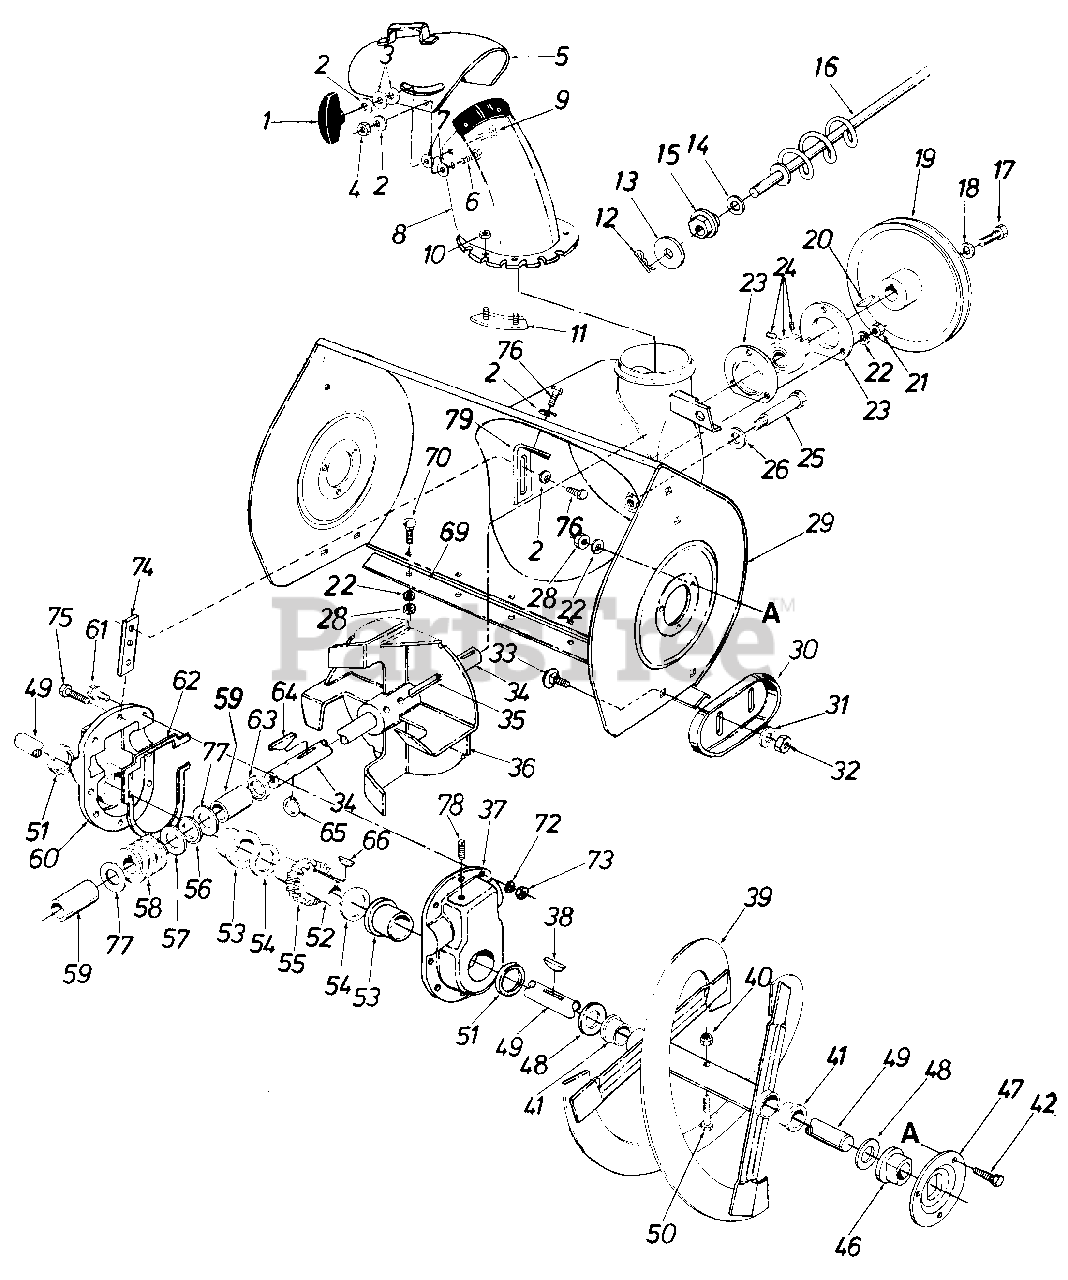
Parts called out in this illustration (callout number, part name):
1	Hand Knob Ass'y.
2	Bell-Wash. .345 0 I.D. x .88 O.D. x .060
3	Fl. Wash. .312 I.D. x 1.125 O.D. x .125
4	Hex Cent. L-Nut 5/16-18 Thd.
5	Top Chute Ass'y.
6	Carr. Bolt 5/16-18 x .62" Lg.
7	Fl-Wash. .53 0 I.D. x 1.25 O.D. x . 1 00
8	Chute Ass'y.
9	Carr. Bolt 5/16-18 x 1.00" Lg.
10	Hex Cent. L-Nut 1/2-20 Thd.
11	Chute Flange Keeper Ass'y.
13	Fl-Wash. .390" I.D. x 1.50" O.D.
14	Fl-Wash. .385" I.D. x .62" O.D.
16	Chute Crank Ass'y.
17	Hex L-Scr. 5/16-18 x .88" Lg.
18	Bell-Wash. .345 0 I.D. x .88 O.D. x .060
19	V-Pulley .875 0 I.D. x 10.12 O.D.
20	#9 Hi-Pro Key 3/16 x 3/4 " Dia.
21	Hex Nut 5/16-18 Thd.*
22	L-Wash. 5/16" Scr.*
23	Bearing Hsg. Self Aligning Brg
24	Self Aligning Brg. .875 I.D.
25	Stud 3/8-16 x 2.75" Lg.
26	Bell-Wash. .400 I.D. x .88 O.D. x .060
28	Hex Nut 5/16-18 Thd.*
29	Blower Hsg. Ass'y.
30	Slide Shoe
31	Bell-Wash. .400 I.D. x .88 O.D. x .060
32	Hex Jam Nut 3/8-16 Thd.
33	Carr. Bolt 3/8-16 x .62" Lg.
35	Spring Pin Spiral 5/16" Dia x 1.75" Lg.
38	#91 Woodruff Key 1/4" x 3/4" Dia.
41	Plastic Bushing
42	Hex Sems Scr. 5/16-18 x .75"*
46	Flange Brg. w/ Flats 1.0" I.D.
47	Bearing Hsg. Spiral Hsg.
48	Fl-Wash. 1.06 I.D. x 1.75" O.D. x .100
49	Spiral Axle 26"
50	Hex Bolt 5/16-18 x 1.75" Lg.
51	Oil Seal 1.50" I.D.
52	Worm Gear Shaft
53	Flange Brg. 1.503 0 I.D.
54	Fl-Wash. 1.50 I.D. x 2.00 O.D. x .030
55	Double Threaded Worm Gear
56	Thrust Brg. .88 I.D. x 1.44 O.D. x .078
57	Fl-Wash. .88 I.D. x 1.40 O.D. x .1 50
58	Double Threaded Worm
59	Sleeve Brg. .875 0 I.D.
60	Complete Gear Hsg. Half R.H.
61	Hex Scr. 5/16-18 x 1.00" Lg.
62	Gasket
63	Oil Seal .875" I.D.
64	#9 Hi-Pro Key 3/16 x 3/4 " Dia.
65	Snap Ring for.875" Dia. Shaft
66	#91 Woodruff Key 1/4 x 3/4" Dia.
72	Wave Wash. 5/16" Scr.*
73	Hex Ins. L-Nut 5/16-18 Thd.
74	Gear Hsg. Support Plate
75	Hex Scr. 5/16-18 x 1.25" Lg.
76	Hex Wash. Hd. Self-Tap Scr. 5/16-18 x .75" Lg.
77	Fl-Wash. .88 I.D. x 1.40 O.D. x . 1 50
